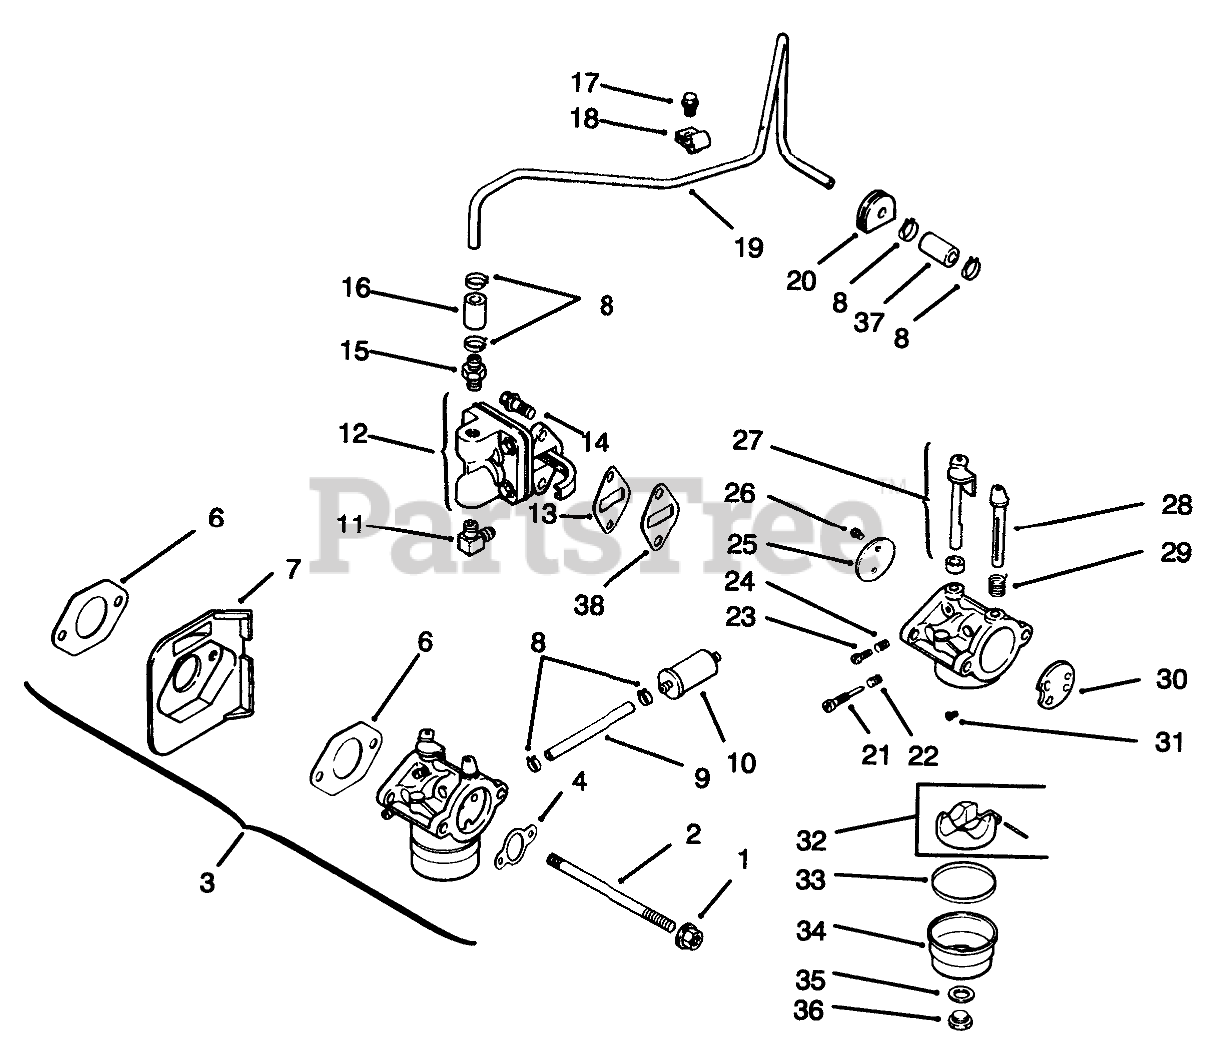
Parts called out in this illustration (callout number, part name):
2	Stud
4	Gasket-Air Cleaner
5	Carurator ASM Incl 21-36
6	Gasket-Carburetor
7	Deflector-Heat
8	Clamp
9	Line-Fuel
10	Filter-Fuel
11	Connector
12	Kit-Pump INC 13-14
13	Gasket-Fuel Pump
14	Screw
15	Connector
16	Line-Fuel
18	Clip, tube
19	Line-Fuel
20	Grommet
21	Needle-Idle
22	Spring-Idle
23	Screw-Idle
24	Spring-Idle
25	Plate-Choke
26	Screw
27	Shaft-w/Lever & Seal
28	Shaft-Choke
29	Spring-Choke Return
30	Plate-Choke
31	Jet-Main
32	Kit-Float
33	Gasket-Bowl
34	Bowl-Fuel
35	Gasket-Bowl
36	Screw-Bowl
37	Line-Fuel 3"
38	Spacer
